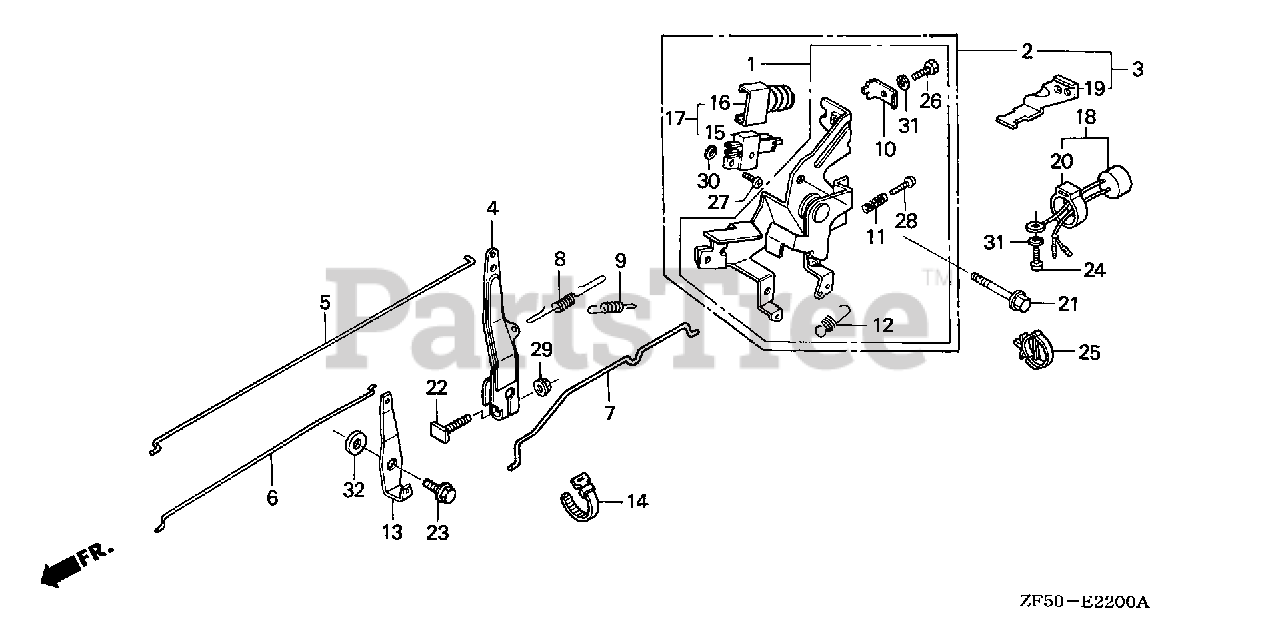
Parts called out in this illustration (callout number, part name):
2	CONTROL ASSY.
4	ARM, GOVERNOR
5	ROD, GOVERNOR
6	ROD, CHOKE
7	ROD, JOINT
8	SPRING, GOVERNOR
9	SPRING, GOVERNOR PRIMARY
10	HOLDER, CABLE
11	SPRING, CONTROL ADJUSTING
12	SPRING, CABLE RETURN
13	LEVER, CHOKE JOINT
14	BAND B1, WIRE
15	SWITCH ASSY., ENGINE
16	COVER, SWITCH
17	SWITCH ASSY., ENGINE STOP
21	BOLT, FLANGE (6X12) (CT200)
22	BOLT, GOVERNOR ARM
23	BOLT, FLANGE (6MM)
26	BOLT, RECESSED (5X14)
26	BOLT, RECESSED (5X16)
27	SCREW, PAN (4X14)
28	SCREW, PAN (5X20)
29	NUT, FLANGE (6MM)
30	WASHER, SPRING (4MM)
31	WASHER, SPRING (5MM)
